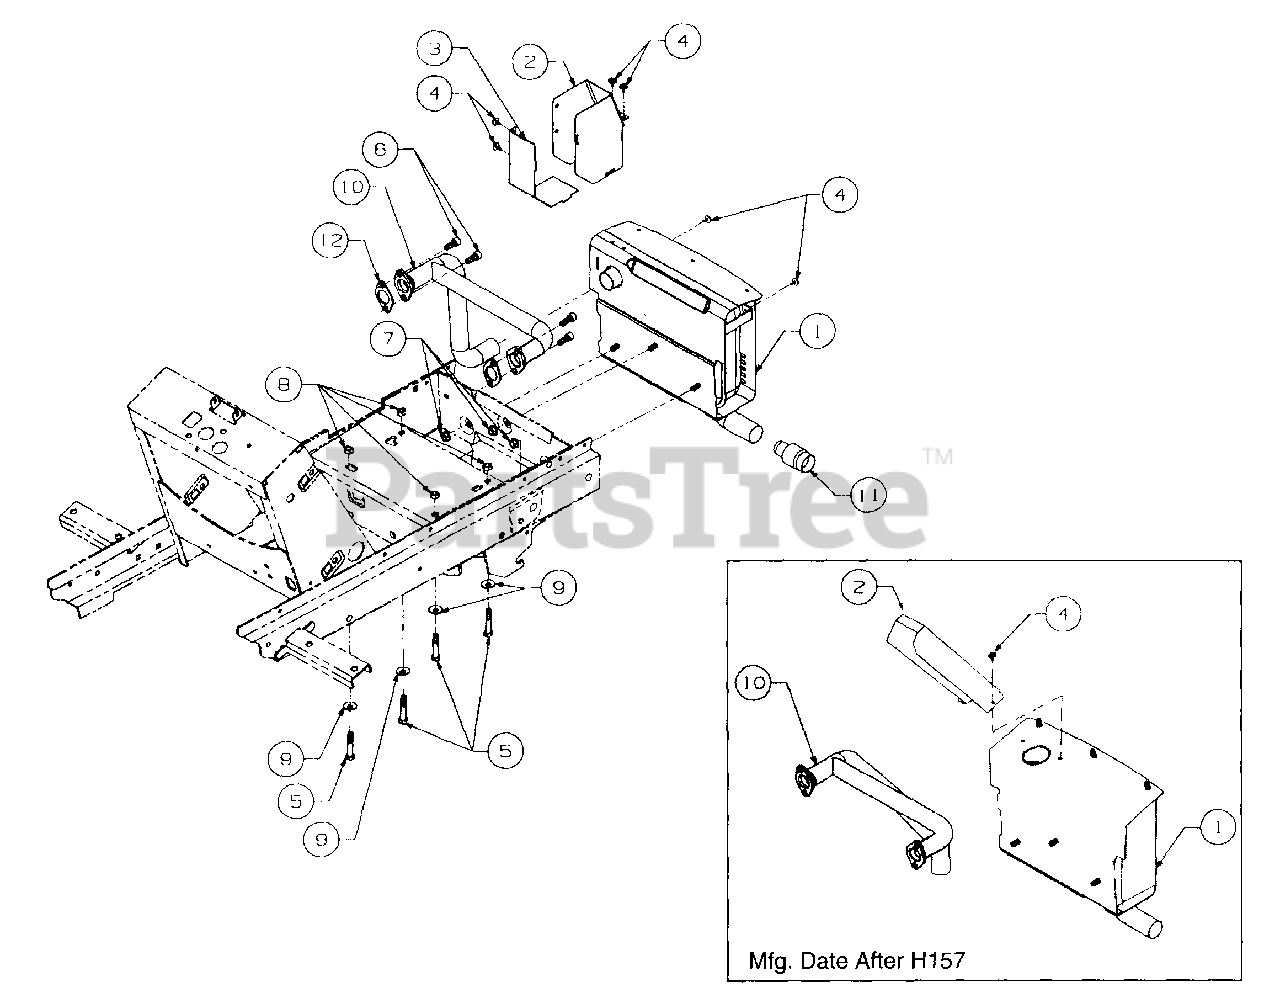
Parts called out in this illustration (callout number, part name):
1	Muffler Assy
2	Shield, Exh.
3	Shield, Rear Exh.
4	Screw, Hex Wash Hd Tapp, #10-16 x .38
5	Bolt, Engine Mnting, 5/16-18 x 1.75 GR5
6	Screw,Socket Hd Cap, M8-1.25 x 20mm
7	Nut, Hex Flange Lock, 5/16-18
8	Nut, Hex, 5/16-18 GR5
9	Washer, Bell, .345 x .88 x .060
10	Tube, Exhaust
11	Arrestor, Spark
12	Gasket, Exhaust
